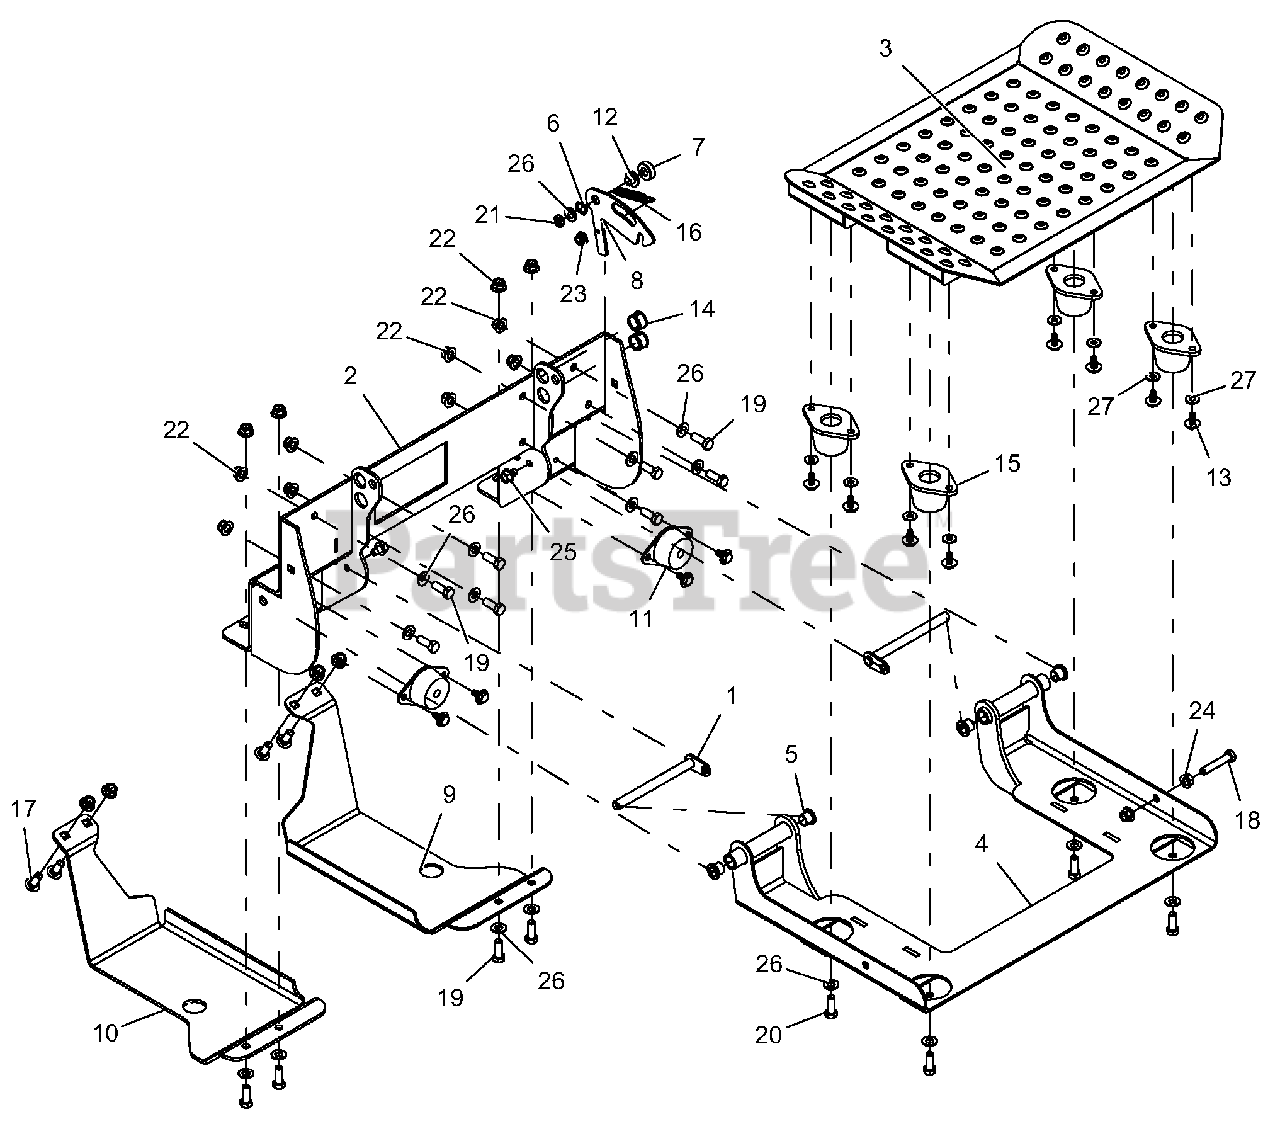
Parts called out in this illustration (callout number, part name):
1	WLDMT, PIN & LOCK
2	WLDMT, PLATFORM SUPPORT - RED
3	WLDMT, PLATFORM TOP - RED
4	WLDMT, PLATFORM CARRIER - RED
5	BRG, FLG .500 x .620 x .500 BRNZ
6	WAVE WASHER .531 x .781 x .125 FH
7	SPCR, .375 x 1.00 x .342
8	LATCH, PLATFORM SIDE
9	PLATE, TRANS SKID, RH
10	PLATE, LH SKID (BLACK)
11	MOUNT, ENGINE. VIBRATION ISO
12	BSHG, FLG .385 x .500 x .875 x .406
13	BOLT, 5/16-18 x .625 SLF TAP FLG
14	BUSH, PANEL SNAP .687 x .875 x .56
15	MOUNT, ISOLATOR
16	SPRG, EXTENSION
17	BLT-RDHDSQNK .38-16 x 1.00 G5 YWZC
18	BLT-HEX .38-16 x 2.00 GR5 YWZC
19	BLT-HEX .38-16 x 1.00 GR5 YWZC
20	BLT-HEX .38-16 x 1.00 GR5 YWZC EP30
21	@NUT-LK-CTR-JAM .375-16 YWZC
22	NUT-LK-NYL-FLG .38-16 YWZC
23	NUT-LK-NYL-FLG .31-18 YWZC
24	@NUT-SPNLK-FLG .375-16 YWZC
25	SCR-TAP .38-16 x .50 HWH TR YWZ
26	WSHR-FL-STL .406 x .812 x .065 YWZ
27	WSHR-FL-STL .312 x .734 x .065 YWZ
